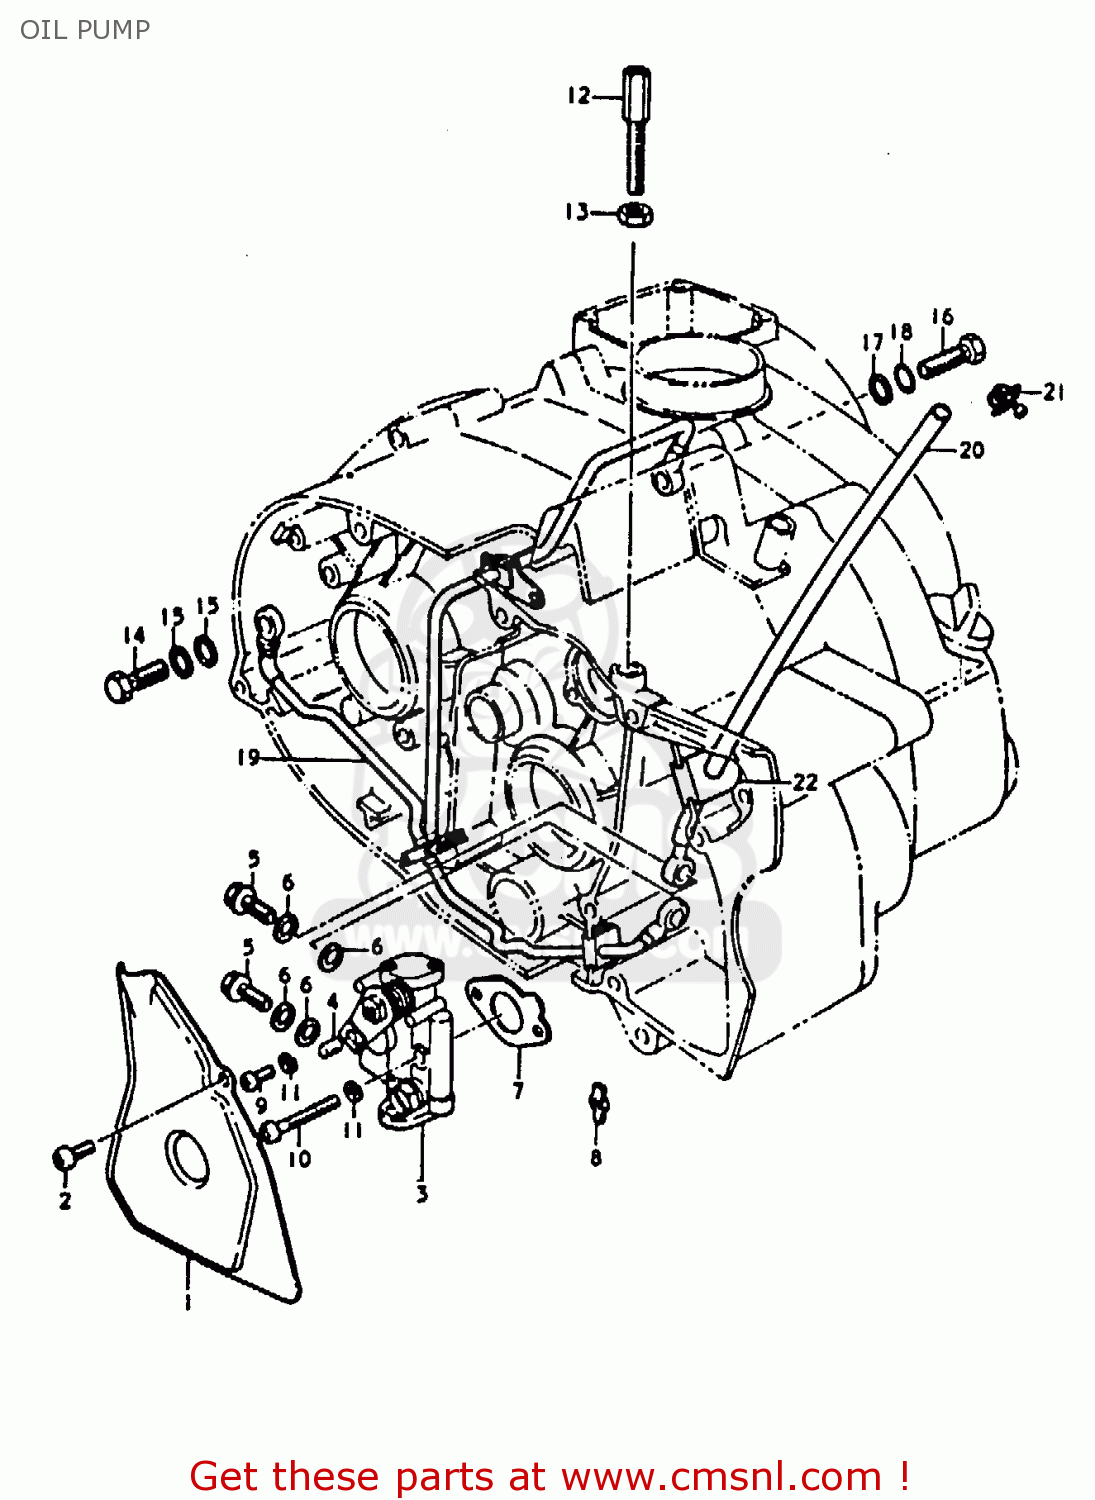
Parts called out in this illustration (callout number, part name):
1	CAP,OIL PUMP INSPECTION
2	SCREW
3	PUMP ASSEMBLY,OIL
4	TERMINAL,CABLE
5	UNION
6	GASKET (NAS)
7	GASKET,OIL PUMP (MCA)
8	PIECE,OIL PUMP DRIVE
9	SCREW
10	SCREW
11	LOCK WASHER
12	BOLT
13	NUT
14	UNION BOLT
15	GASKET (NAS)
16	CHECK VALVE,INLET
17	GASKET(10X16X3) (NAS)
18	O RING(D:1.3,ID:7.6)
19	HOSE
20	HOSE,OIL NO.1
21	CLAMP
22	GROMMET
